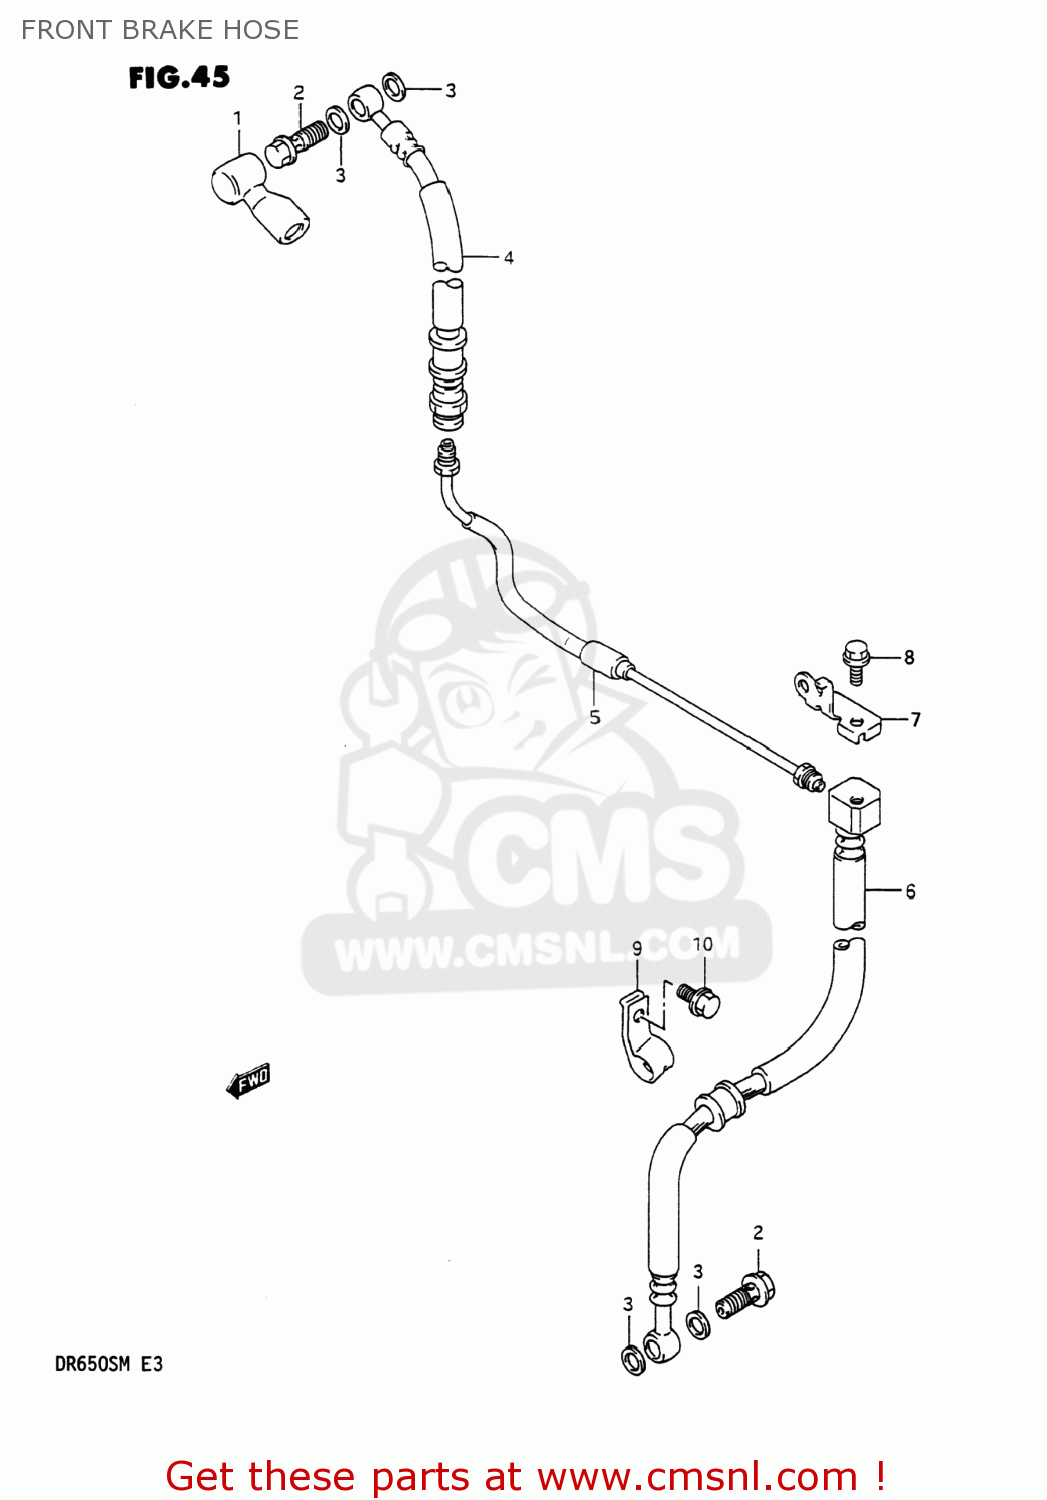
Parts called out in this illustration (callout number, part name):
1	BOOT,MASTER CYLINDER
2	BOLT UNION
3	WASHER(10X15X1.5)
4	HOSE COMP,FRONT BRAKE
5	PIPE COMP,FRONT BRAKE
6	HOSE COMP,FRONT BRAKE
7	BRACKET,FRONT BRAKE HOSE
8	BOLT
9	CLAMP,FR BRAKE HOSE NO.2
10	BOLT
